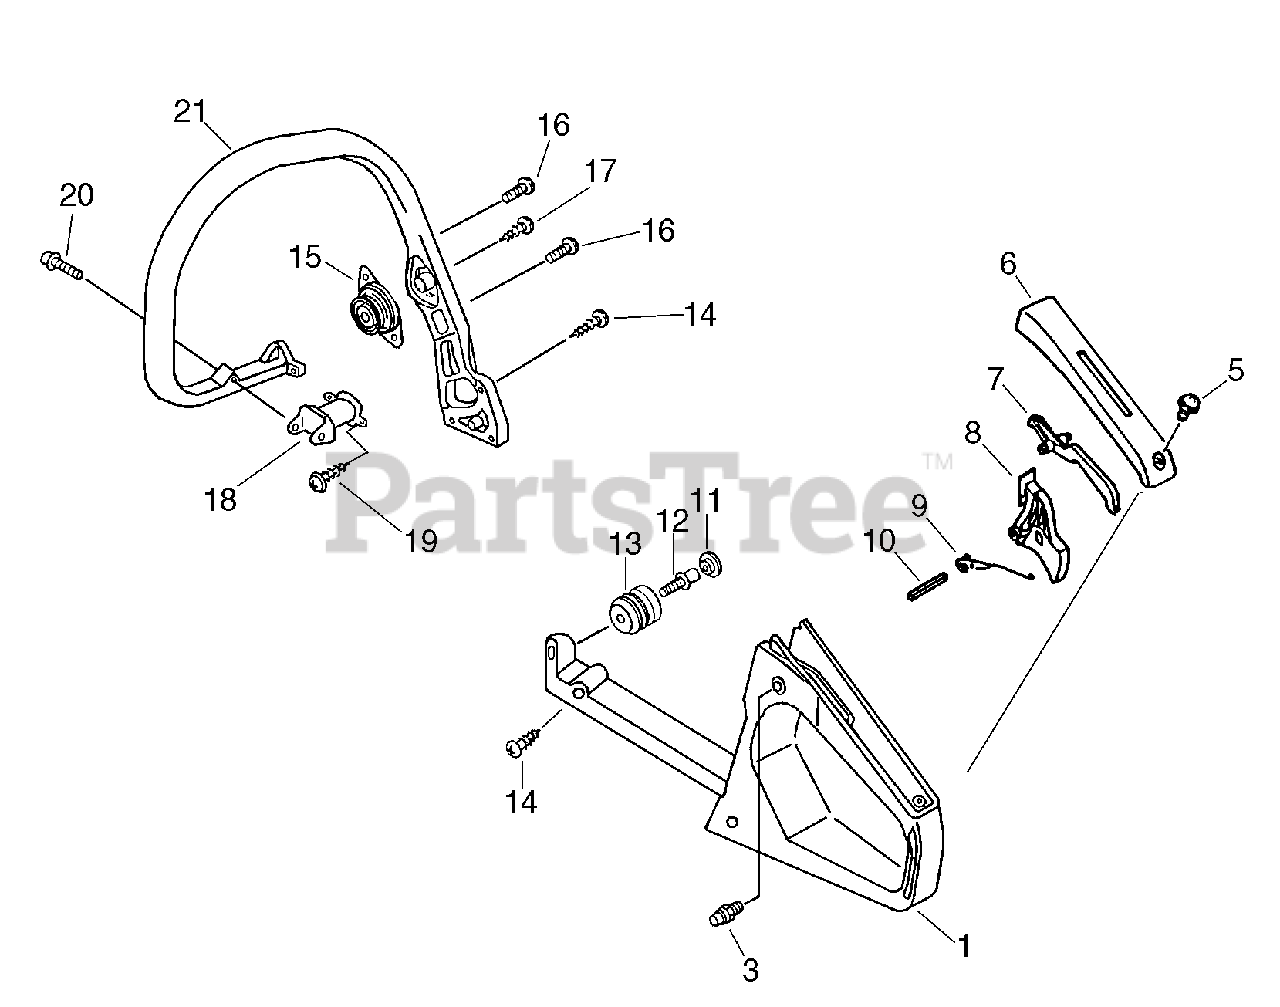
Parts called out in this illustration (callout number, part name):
1	HANDLE, REAR
3	LOCK, THROTTLE TRIGGER
5	SCREW 4×12
6	COVER, HANDLE
7	LEVER, THROTTLE LOCKOUT
8	TRIGGER, THROTTLE
9	SPRING, THROTTLE RETURN
10	PIN, SPRING 4×30
11	CAP, CUSHION
13	CUSHION 5
14	SCREW, TAPPING 5×20
15	CUSHION, REAR HANDLE
16	SCREW 4×16
17	SCREW 5×16
19	SCREW 4×12
20	SCREW 4×22
21	HANDLE, FRONT
